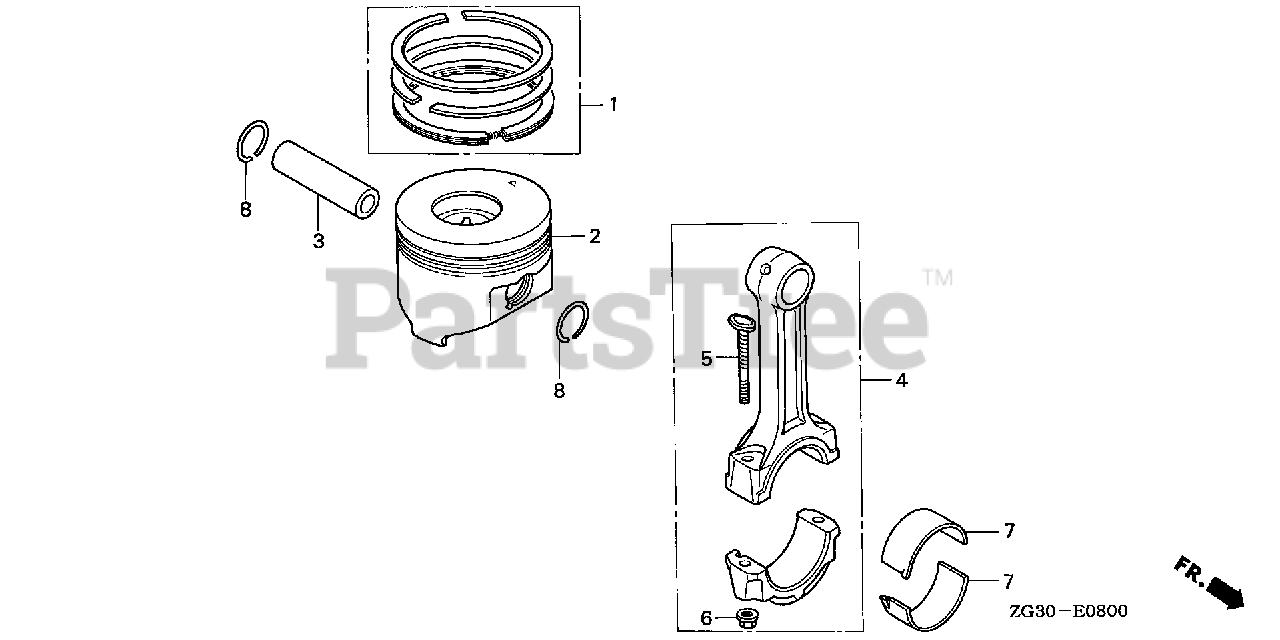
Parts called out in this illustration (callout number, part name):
1	RING SET, PISTON (STD)
1	RING SET, PISTON (0.25)
1	RING SET, PISTON (0.50)
1	RING SET, PISTON (0.75)
2	PISTON (STD)
2	PISTON (0.25)
2	PISTON (0.50)
2	PISTON (0.75)
3	PIN, PISTON
4	ROD ASSY., CONNECTING
5	BOLT, CONNECTING ROD (8X51)
6	NUT, CONNECTING ROD
7	BEARING A, CONNECTING ROD (BLUE)
7	BEARING B, CONNECTING ROD (BLACK)
7	BEARING C, CONNECTING ROD (BROWN)
7	BEARING D, CONNECTING ROD (GREEN)
7	BEARING E, CONNECTING ROD (YELLOW)
7	BEARING, CONNECTING ROD (F)(PINK)
7	BEARING G, CONNECTING ROD (RED)
7	BEARING A, CONNECTING ROD (UNDER SIZE 0.25) (BLACK)
7	BEARING B, CONNECTING ROD (UNDER SIZE 0.25) (BROWN)
7	BEARING C, CONNECTING ROD (UNDER SIZE 0.25) (GREEN)
7	BEARING A, CONNECTING ROD (UNDER SIZE 0.50) (BLACK)
7	BEARING B, CONNECTING ROD (UNDER SIZE 0.50) (BROWN)
7	BEARING C, CONNECTING ROD (UNDER SIZE 0.50) (GREEN)
7	BEARING A, CONNECTING ROD (UNDER SIZE 0.75) (BLACK)
7	BEARING B, CONNECTING ROD (UNDER SIZE 0.75) (BROWN)
7	BEARING C, CONNECTING ROD (UNDER SIZE 0.75) (GREEN)
8	CLIP, PISTON PIN
